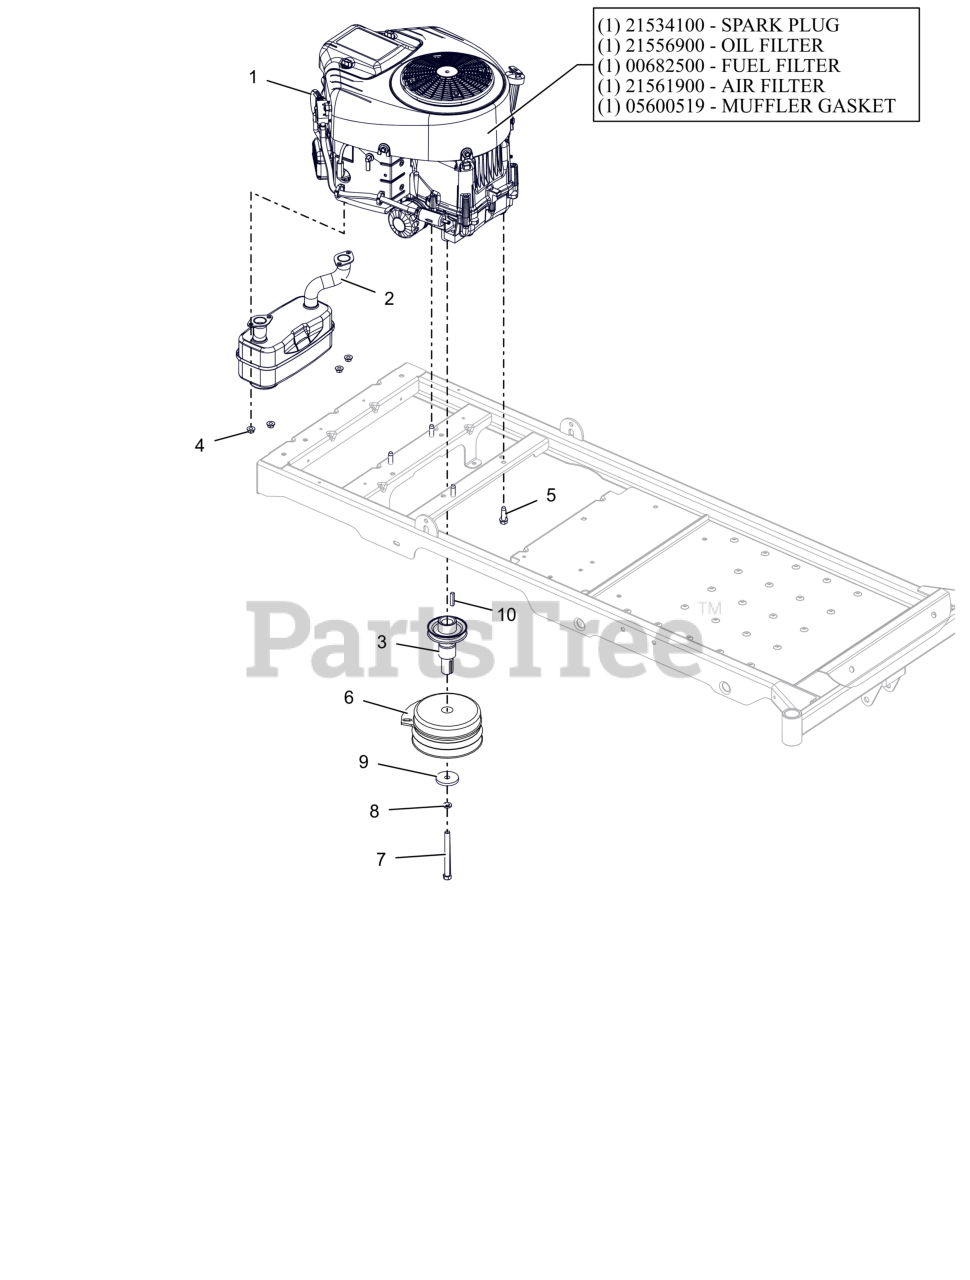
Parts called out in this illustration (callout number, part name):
1	ENGINE, BRIGGS 20 HP
1	PLUG, SPARK
1	OIL FILTER, BRIGGS
1	GASOLINE FILTER, BRIGGS
1	AIR FILTER, BRIGGS
1	GASKET, MUFFLER BRIGGS 690970
2	MUFFLER - TWIN BRIGGS
3	WLDMT, CRANK SHAFT ADAPTER- BRIGGS
4	NUT-LK-TOP-FLG M8 ZCC
5	SCR,TAP .375-16X1.25HWH TR ZCC
6	CLUTCH, 105 FT*LB MONO POLE
7	BLT, HEX .44-20X4.50 G8 ZCC NT
8	WSHR, LK-REG .438X.109 ZCC
9	WSHR, FLT .469X2.00X.250 ZCC
10	KEY-SQ .25 X 1.25 X .25 SAE
